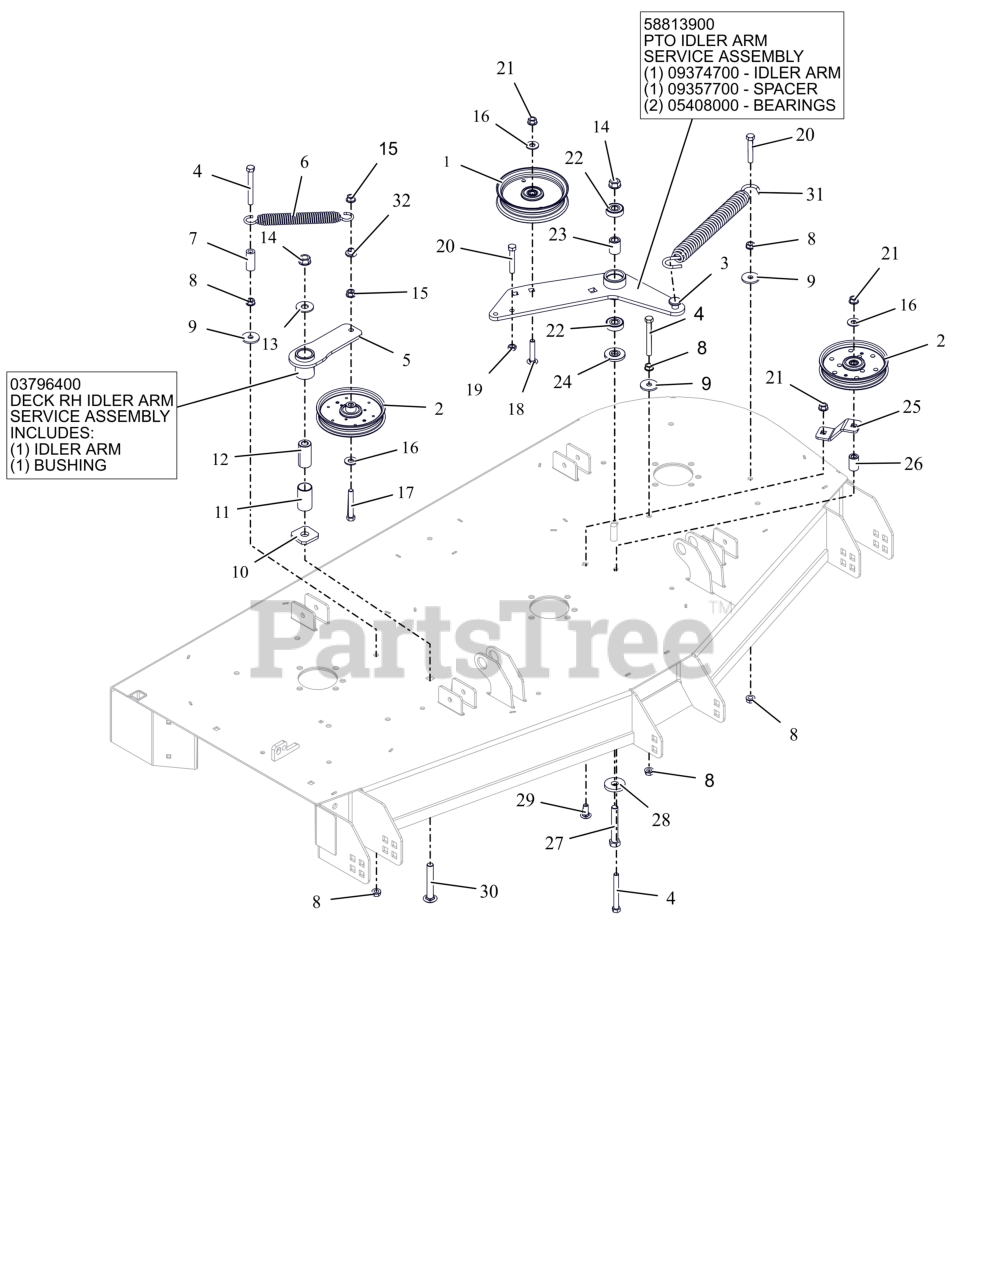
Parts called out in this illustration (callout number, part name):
1	IDLER- FLAT - 5.00" X .75"
2	IDLER- 5" FLANGED
3	WLDMT, IDLER ARM PT660
4	BLT, HEX .38-16X3.25 G5 ZCC
5	WMT, IDLER ARM - BLACK
6	SPRING- EXTENSION
7	HOSE, .38 X 1.65
8	NUT, SPNLK-FLG .38-16 G5 ZCC
9	WSHR,FLT .406X1.375X.135 ZCC
10	WSHR-FLT .640X1.75X.250
11	BSHG, 1.00X1.125X1.937
12	BSHG, SPCR .502X.997X2.03 PM
13	WSHR,FLT .563X1.375X.109 ZCC
14	NUT-LK-CTR-FLG .500-13 GG ZCC
15	NUT-LK-CTR-FLG .375-16 GF ZCC
16	WSHR,FLT .438X1.00X.083 ZCC
17	BLT, HEX .38-16X2.50 G5 ZCC
18	BLT,RHSSN.375-16X2.00 G5 ZCC
19	NUT-JAM .375-16 G2 ZCC
20	BLT,HEX .38-16X2.25 G5 ZCC
21	NUT-LK-CTR-FLG .375-16 GF ZCC
22	BRG-BALL .500X1.38X.437
23	SPACER .510 X .867 X 1.1485
24	SPACER, IDLER ARM
25	PTO FIXED IDLER MTG BRKT-ORG
26	BUSHING, SLV .380X.750X1.190
27	BLT,HEX .50-13X3.25 G5 ZCC
28	WSHR-FL-STL 0.557X1.625X0.25 ZCC
29	BLT,RHSSN .38-16X1.00 G5 ZCC
30	BTL,RHSSN .500-13 X 3.25 G5 ZCC
31	SPRING, EXTENSION
32	BSHG-FLG .385X.500X.875X.406
